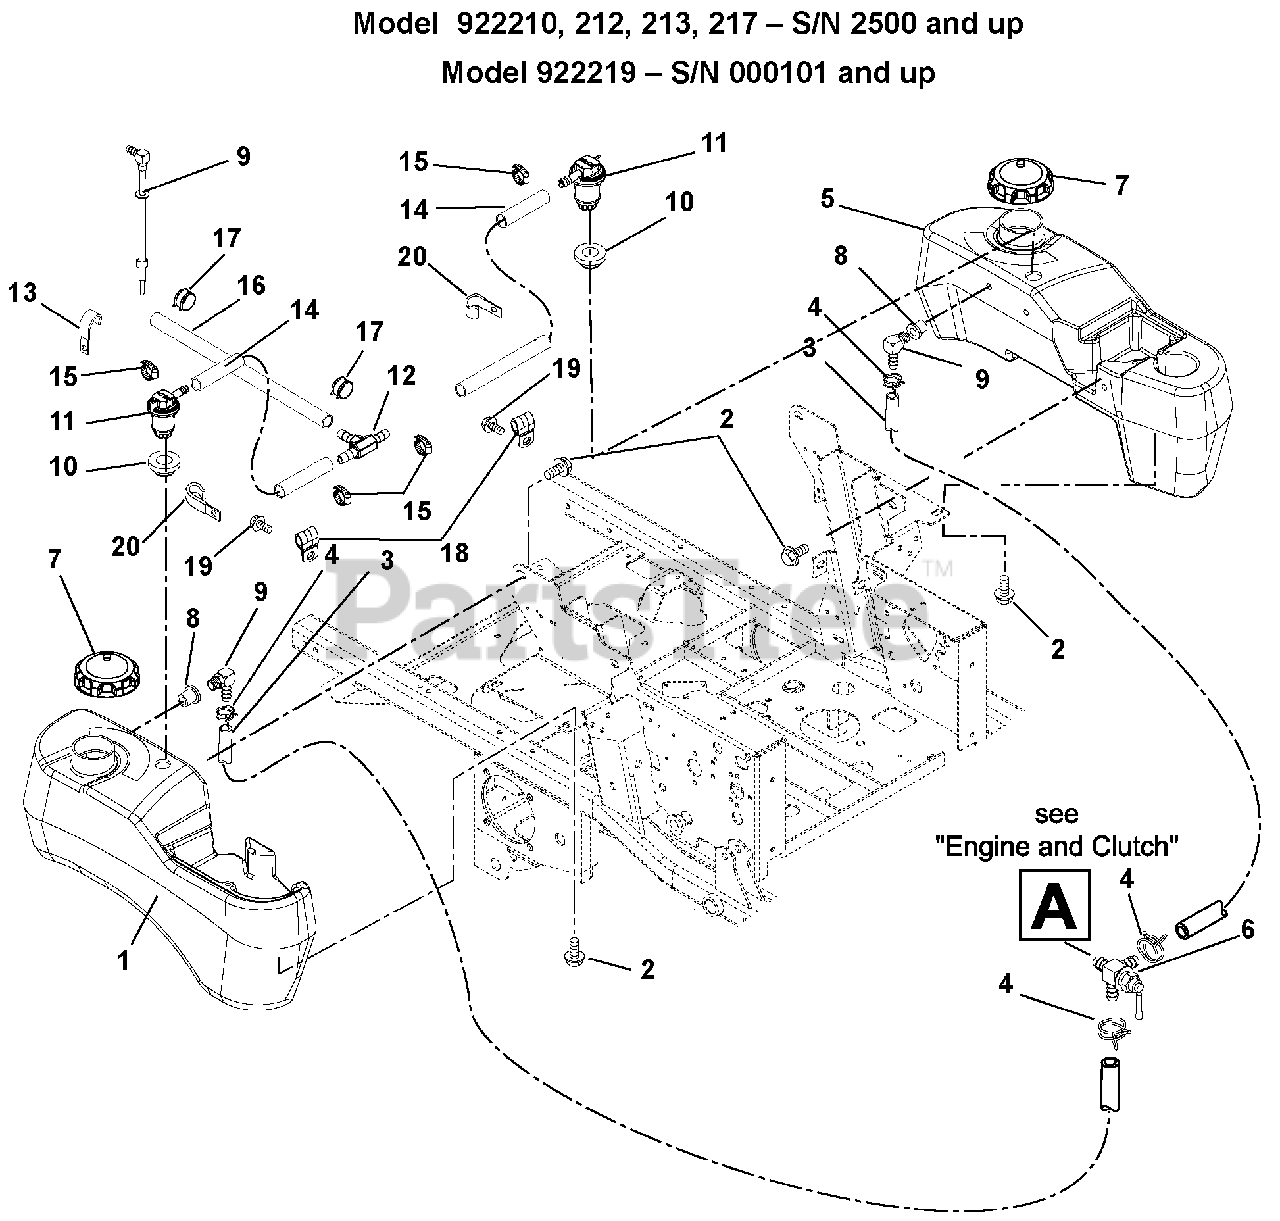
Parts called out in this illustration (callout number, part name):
1	Tank, Fuel – Right Hand
2	Bolt, SEMS .31-18 x .62
3	Hose, .25 Low-PERM Bulk Gas (3 @ 42 in.)
4	Clamp, Fuel Line
5	Tank, Left Hand Fuel
6	Valve, Fuel
7	Cap, Vent-in Ratchet Fuel
9	Assembly, Large Tank Fuel Pick-up
10	Grommet, Remote Vent Nitrile
11	Valve, Combination
12	Fuel Tee, .25 HS Run x .18 HS Branch
14	Hose, .25 Low-PERM Bulk Gas
15	Clamp, Fuel Line
16	Hose, .188 Low-PERM Bulk Gas
17	Clamp, Hose Spring .188
18	Clamp, Cushioned Steel
19	Screw, Tapping .31-18 x .50 Hex Washer Head Thread Rolling
